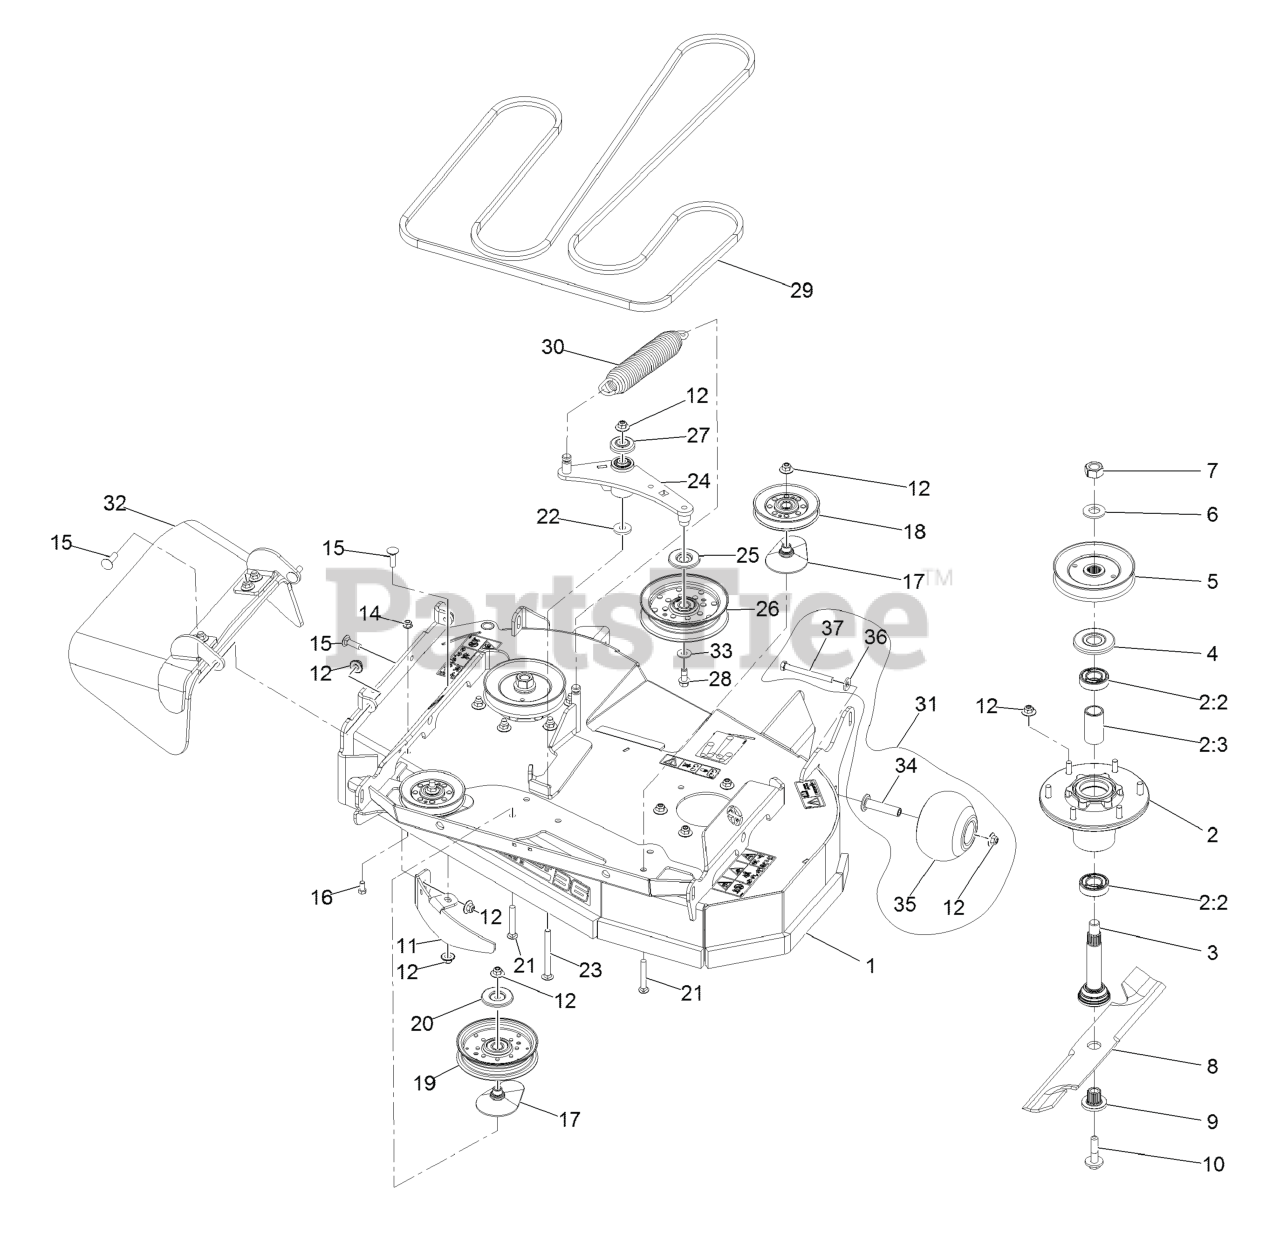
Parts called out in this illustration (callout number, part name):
1	ASM, 36" DECK W/ DECALS
2	ASM-CUTTER HSG WITH BEARINGS
2:2	BEARING-BALL
2:3	SPACER-BEARING
3	ASM-SPINDLE AND SEAL
4	GUARD,BEARING TOP .989
5	SHEAVE-BLADE DRIVE
7	NUT-HEX
9	BUSHING,SPLINED
10	SCREW,SEMS 1/2-20 X 2.19
11	BAFFLE, DOGLEG
12	Nut-Nyloc 3/8-16 Flg
14	NUT-HF, NI
15	BOLT-CARR
16	SCREW-HH
17	SPACER-PULLEY
18	Idler - V 4.13 Eod-A
19	PULLEY-IDLER, FLAT
20	SHIELD-DUST
21	SCREW-CARR
23	SCREW-CARR
24	ASM.-ARM, IDLER
25	SHIELD-GUARD, DUST
26	IDLER-PULLEY, FLAT
27	GUARD-TOP
28	SCREW-HFH
30	SPRING-EXTENSION
31	KIT, ANTI-SCALP ROLLER
32	RUBBER DEFLECTOR ASM
33	WASHER-FLAT
34	AXLE, ROLLER
35	ROLLER-SCALP, ANTI
36	WASHER-BELLEVILLE
37	SCREW-HH 3/8-16 X 3 3/4 GR 8
